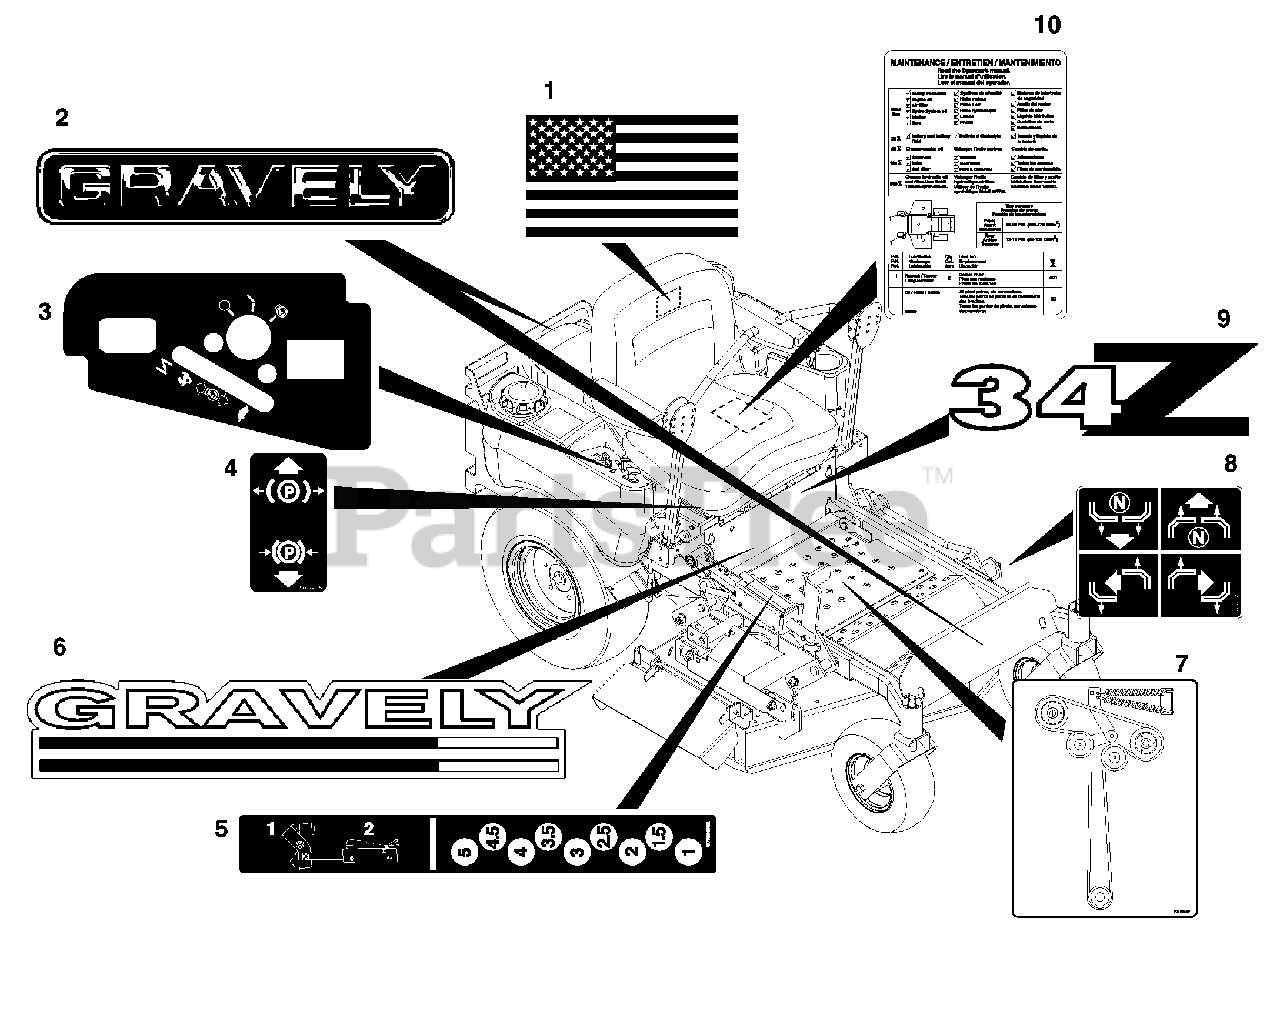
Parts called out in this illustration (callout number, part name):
1	Decal, American Flag
2	Decal, 15" Gravely Logo
3	Decal, Control Panel
4	Decal, Parking Brake Lever
5	Decal, Height of Cut
6	Decal, ZT Hood
7	Decal, Belt Diagram
8	Decal, Instructional Steering
9	Decal, PM 34Z
10	Decal, Service Instructions
